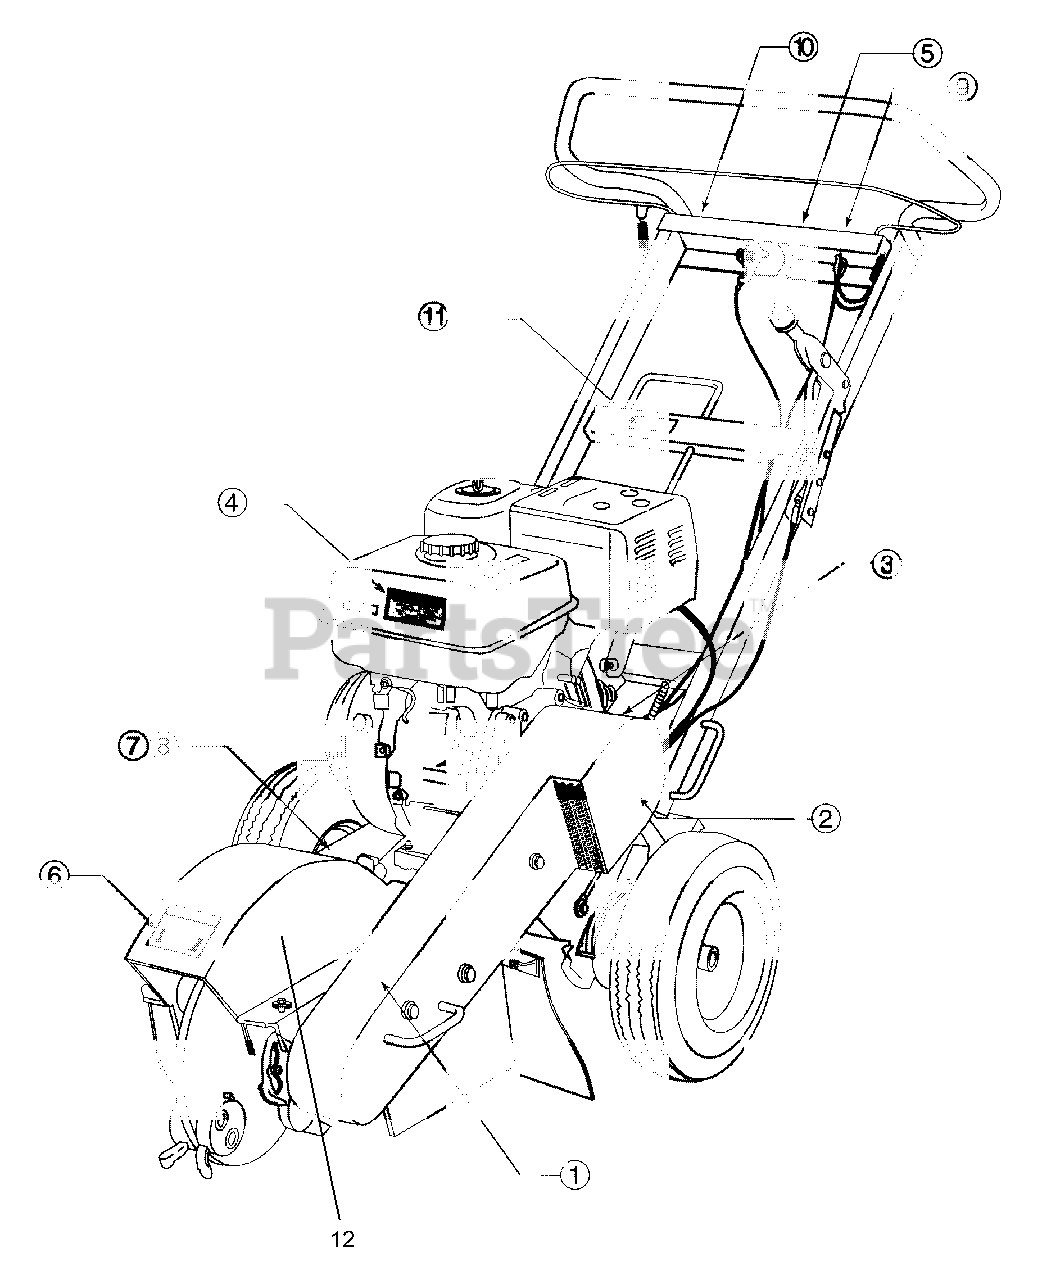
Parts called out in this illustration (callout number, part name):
1	Decal, Husqvarna logo and crown
2	Decal, Crown
3	Decal, Caution list
4	Decal, Warning Carbon monoxide
5	Decal, Eye and hearing
6	Decal, Danger foot
9	Decal, On/Off toggle
10	Decal, Throttle control
11	Decal, Handle adjustment
12	Decal, Nascar
